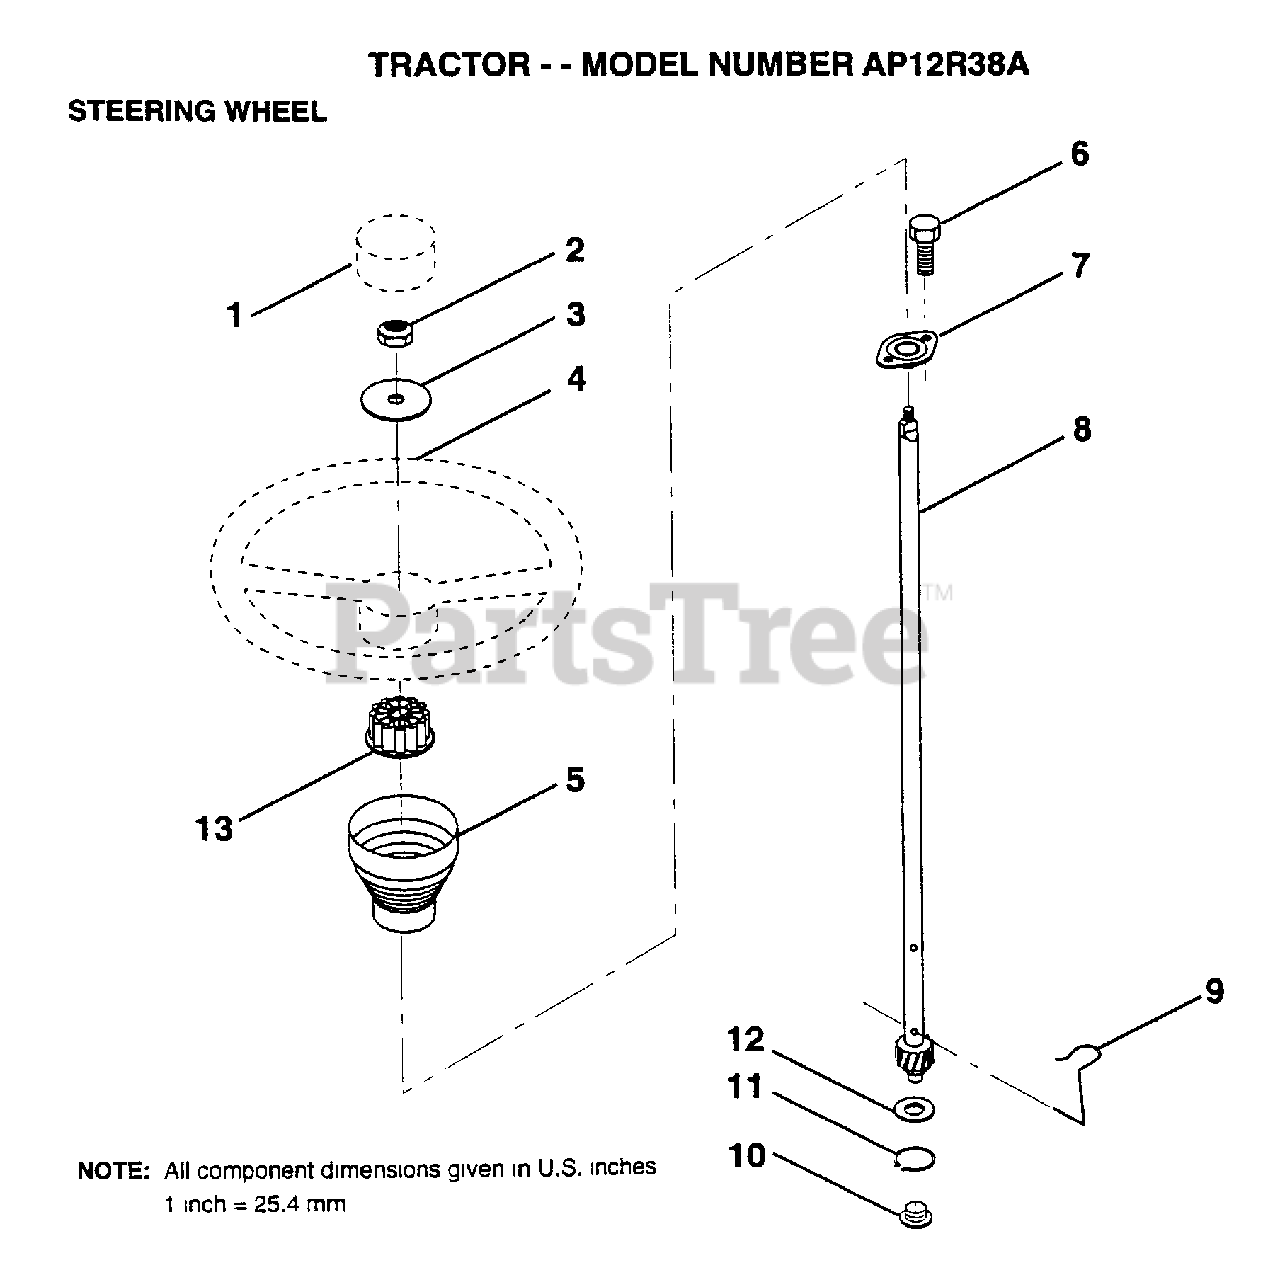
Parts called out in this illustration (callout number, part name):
1	ST WHL INSERT CAP
2	GRIPCO NUT
3	WASHER T
5	SLEEVE STEERING
9	STEERING CLIP
10	BUSHING STEER LWR
11	RING
12	WASHER LT
13	ADAPTER-WHEEL LT
